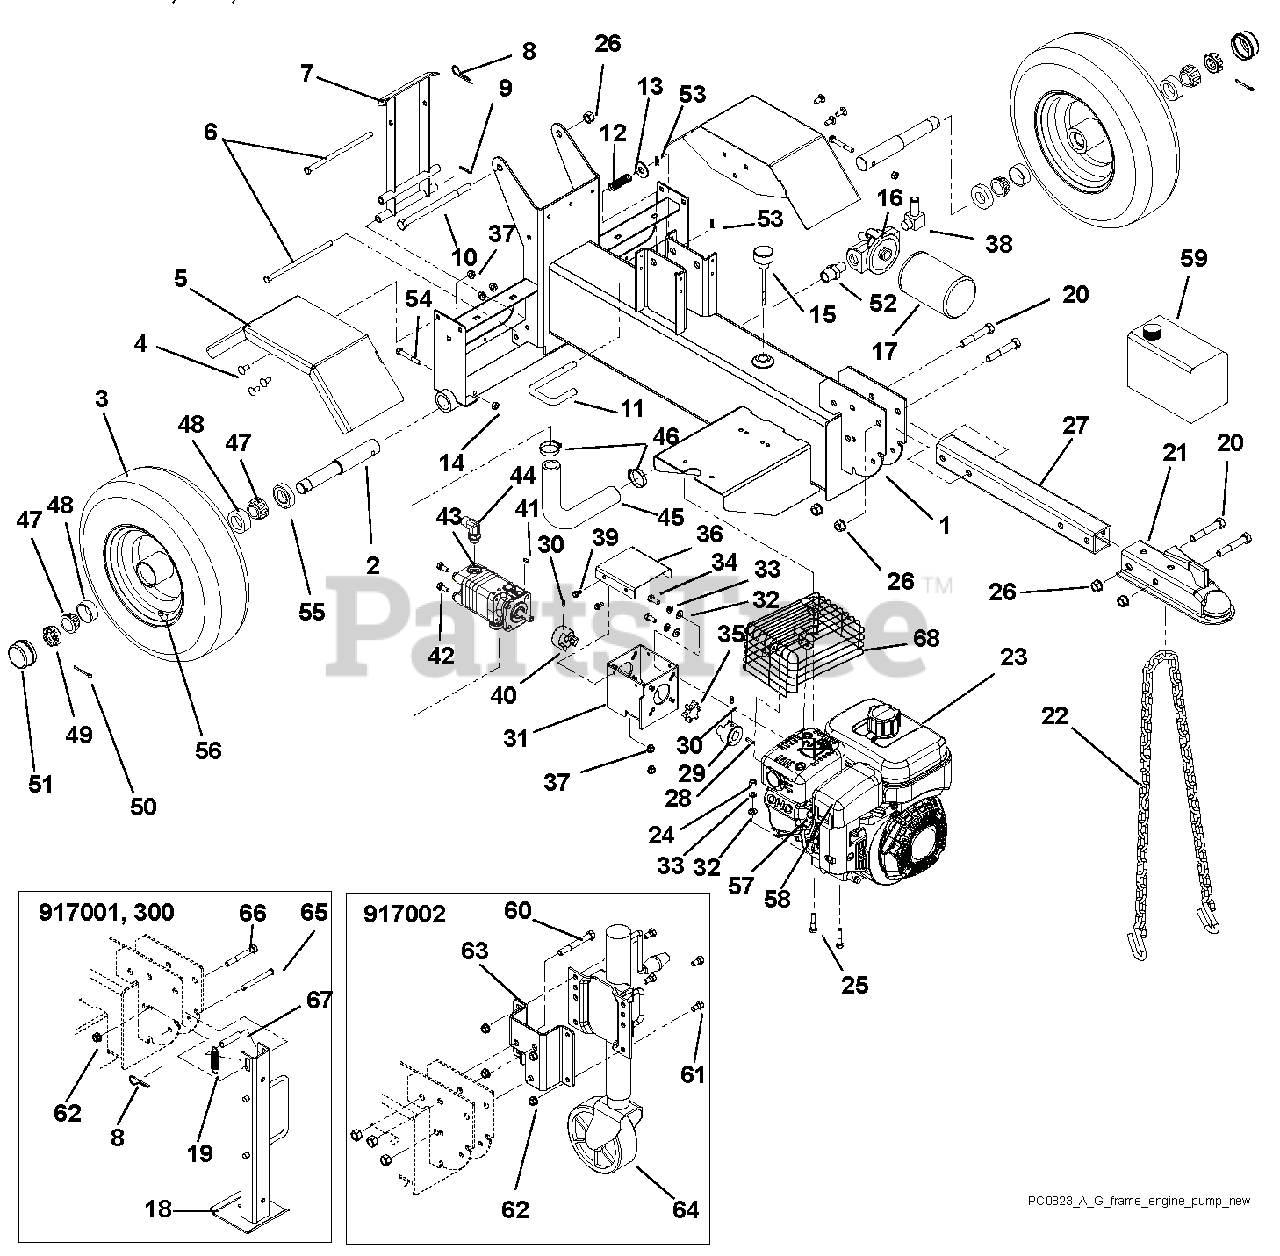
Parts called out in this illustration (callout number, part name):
1	CHASSIS,SPLITTER W/SAFTY DECAL
2	AXLE, SPLITTER
3	WHEEL, SPLITTER
4	@BLT-RDHDSQNK .31-18X.75 G5YZ
5	WLDMT, FENDER
6	PIN, LOCK
7	REAR STAND W/DECALS (ARIENS)
8	HAIRPIN, #7 CLIP .094X2.31 YWZ
9	PIN-HAIR, ENDRIES #25 YWZC
10	@BLT-HEX .50-13X7.50 GR5 YWZC
11	LOCK, BEAM
12	SPRG, COMP .058X.65X2.13 WLD15
13	@WSHR-FL-STL.563X1.38X.109YWZC
14	@NUT-LK-CTR .31-18 YWZC
15	BREATHER, DIPSTICK
16	HEAD,FILTER-3/4 NPT BYPASS
17	FILTER,OIL-W/BYPASS
18	WLDMT, JACK STAND
19	SPRG, TENSION .063X.625X2.50
20	@BLT-HEX .50-13X3.00 GR5 YWZC
21	HITCH, BALL-2"
22	CHAIN, SAFETY
23	ENGINE,SUBARU 6HP SP170 (CARB)
24	@NUT-HEX .31-18 YWZC
25	@BLT-HEX .31-18X1.50 GR5 YWZC
26	@NUT-LK-CTR .50-13 YWZC
27	HITCH BAR W/DECALS
28	KEY-SQ .188X.75X.188
29	HUB,DRIVE COUPLING 3/4"
30	SCR-SET .25-20X.38 SKHCUPNL OH
31	WLDMT, PUMP MOUNT BRKT
32	@WSHR-FL-STL.344X.688X.065YWZC
33	WSHR-LK .312X.097 HVY YWZC
34	BLT-HEX .31-24X.75 YWZC GR5
35	SPIDER,URETHANE
36	COVER W/DECALS
37	@NUT-LK-TOP-FLG .31-18 YWZC
38	FTG,HYD 4501-10-12-FG
39	SCR-TAP .25-20X.50 HWH TR YWZ
40	HUB,DRIVE COUPLING 1/2"
41	KEY-WDRF .125X.50X.20 (HRDEND)
42	@BLT-HEX .31-18X.75 GR5 YWZC
43	PUMP,SPLITTER-11 GPM
44	FTG,HYD 6801-8-8
45	HOSE,HYD SUCTION 16G4H X 13.5
46	CLAMP-HOSE 1.50X.81X1.42
47	BRG, CONE W/ GREASE
48	BRG-CUP1.980X.420
49	NUT-SL 1.0-14
50	@PIN-CTR .15X1.50 YWZC
51	CAP,DUST
52	FTG,HYD 5404-12-12
53	CLIP, SPRING
54	@BLT-HEX .31-18X2.25 GR5 YWZC
56	VALVE STEM ASS'Y
57	SPARK PLUG,SP-170
58	FILTER,SP-170 SPONGE/ROBIN
59	OIL, 2.5 GAL HYD ISO GRADE 32
60	@BLT-HEX .50-13X3.25 GR5 YWZC
61	@BLT-HEX .38-16X.75 GR5 YWZC
62	@NUT-LK-TOP-FLG .38-16 YWZC
63	BRACKET, MOUNTING
64	STAND, JACK-W/WHEEL
65	PIN-CLEV .371X3.25 YWZC
66	@BLT-HEX .38-16X3.00 GR5 YWZC
67	SPCR, WHEEL .385X.500X2.00
68	GUARD,MUFFLER,SUB 20A-37303-11
